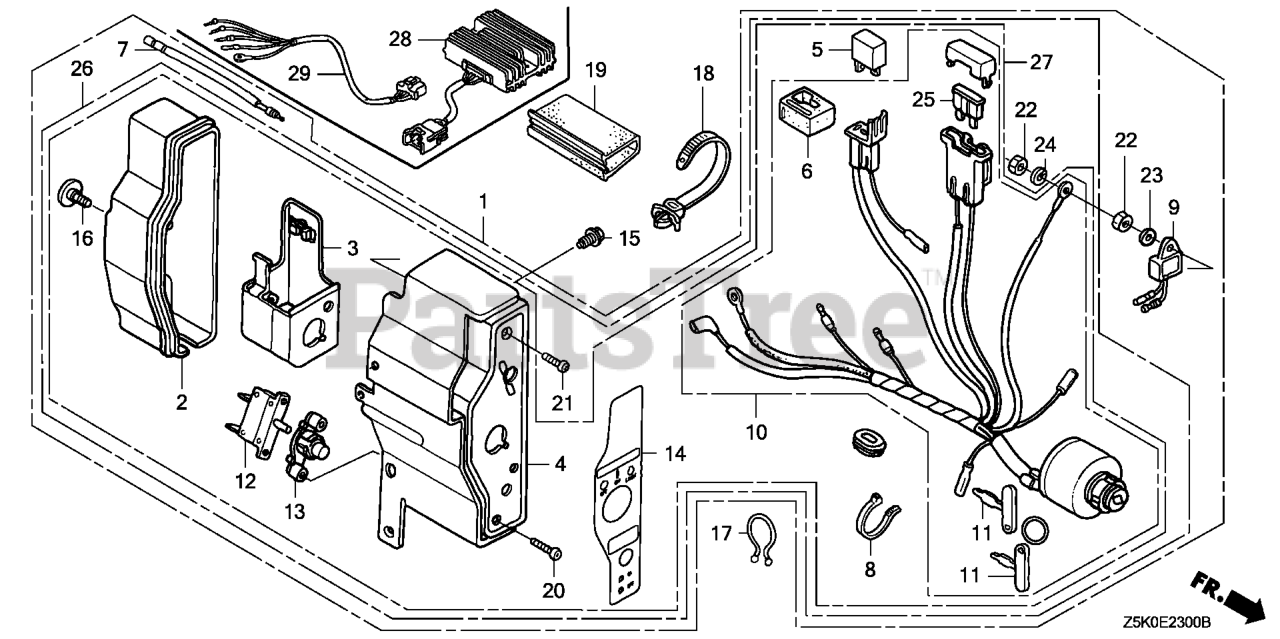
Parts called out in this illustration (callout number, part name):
2	CASE, CONTROL
3	BRACKET, CASE MOUNTING
4	PANEL, CONTROL *R280* (POWER RED)
5	RECTIFIER ASSY., SILICON (SHINDENGEN)
6	SUSPENSION, CONNECTOR
8	BAND
10	SWITCH ASSY., COMBINATION (3A-CHARGE)
11	KEY
12	PROTECTOR, CIRCUIT (3.5A)
13	LENS ASSY., PROTECTOR
14	MARK, CONTROL BOX (EXTERNAL)
15	BOLT, FLANGE (6X12) (CT200)
16	SCREW, SPECIAL (6X12)
17	CLIP, PURSE LOCK
18	STRAP, CABLE (118MM) *NH1L* (Honda Code 1170653). (BLACK)
19	TUBE, FASTENER (30)
20	SCREW, PAN (3X12)
25	FUSE, BLADE (5A)
25	FUSE, BLADE (15A)
27	BOX ASSY., CONTROL (3A) *R280* (EXP-ALERT) (POWER RED)
